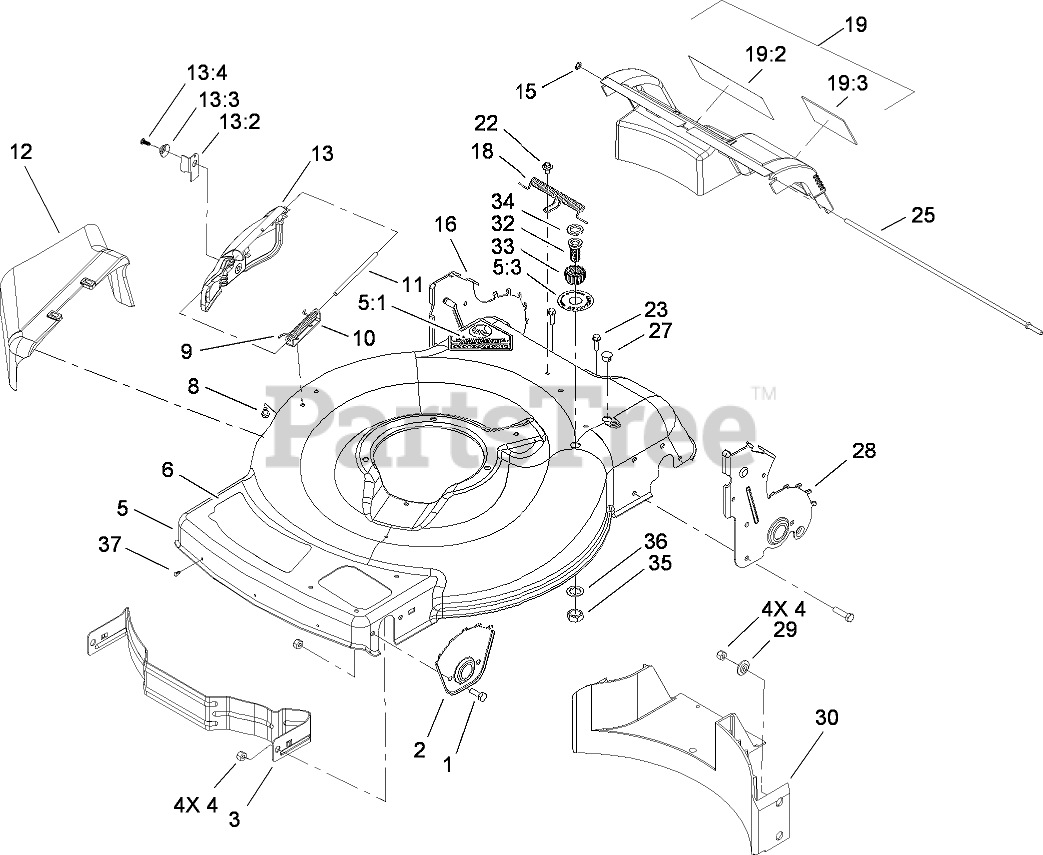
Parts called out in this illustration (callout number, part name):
1	SCREW-HH
2	Plate-HOC, Front
3	Baffle-Front
4	NUT-LOCK, NI
5	HOUSING ASM
5:1	DECAL-DANGER
5:3	DECAL-PORT, WASHOUT
6	DECAL-DECK
8	SCREW-HWH
9	SPRING-TORSION
10	BRACKET-COVER
11	ROD-COVER
12	CHUTE-DISCHARGE, SIDE
13	DISCHARGE DOOR ASM
13:2	LATCH-DOOR
13:3	CAP-DOOR
13:4	SCREW-PLASTITE
15	NUT-PUSH
16	11 INCH RH HOC PLATE ASM
18	Spring-Door, Rear
19	REAR DOOR ASM
19:2	DECAL-WARNING
19:3	DECAL-WARNING
22	SCREW AND WASHER ASM
23	SCREW-HWH
25	Rod-Pivot, Rear Door
27	Plug-Dome
28	11 INCH LH HOC PLATE ASM
29	Washer-Stepped
30	Baffle-Rear
32	PORT-WASHOUT
33	COUPLING-HOSE, WASHOUT PORT
34	WASHER-SEAL, WASHOUT PORT
35	NUT-JAM
36	WASHER-TOOTH, INTERNAL
37	PLUG-ARROW
